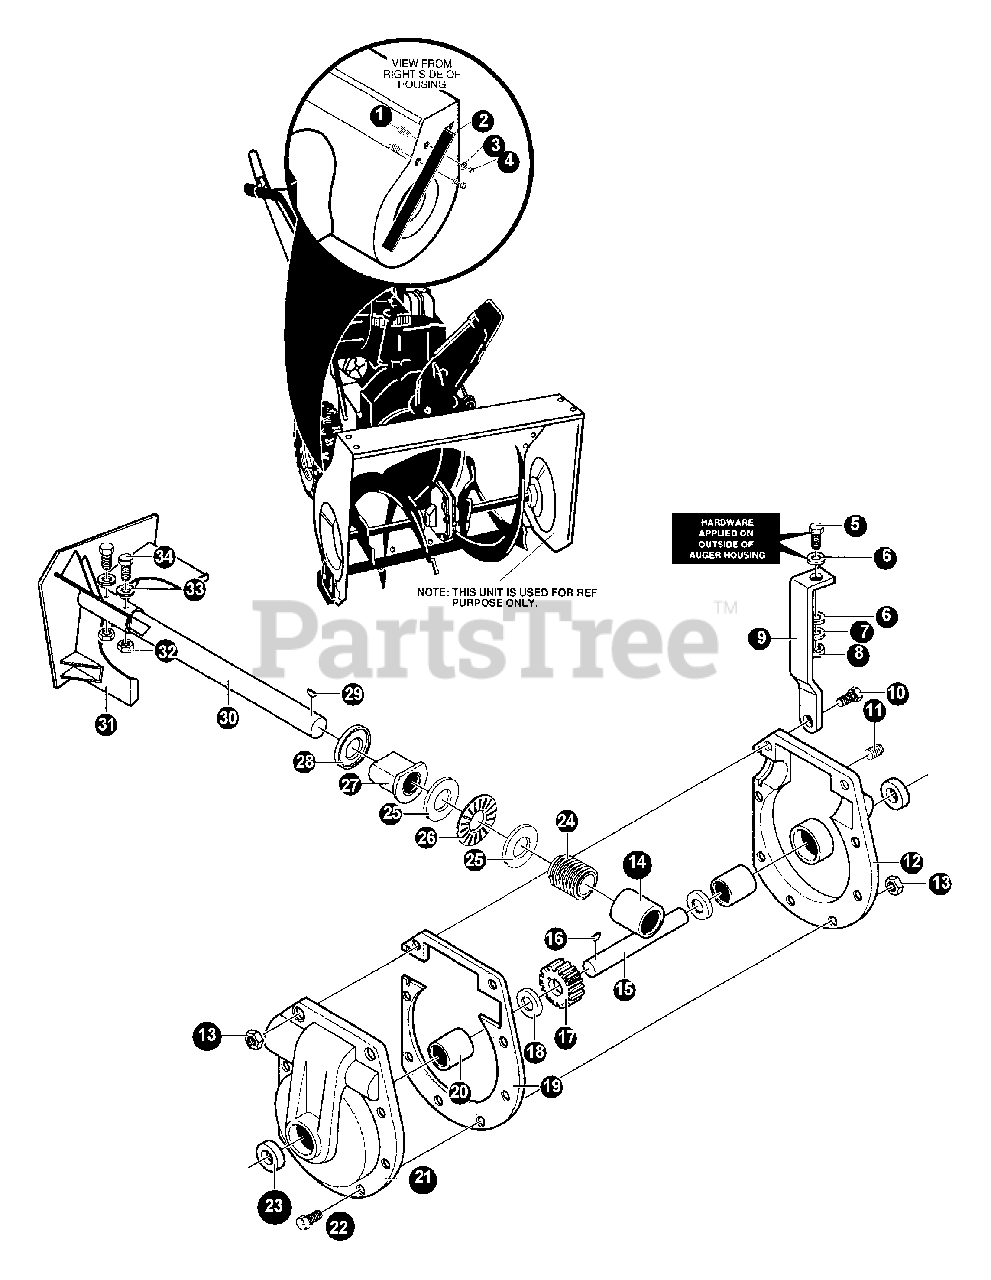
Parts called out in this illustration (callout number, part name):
1	BOLT, CARRIAGE 5/16-18×0.75
2	BAR, DRIFT CUTTER
3	WASHER
5	SCREW - 5/16-18×1.25" -- HEX HEAD CAP
6	WASHER
7	WASHER
9	BRACE, GEAR BOX
10	SCREW - 5/16-24×1.75" -- HEX HEAD CAP
11	PLUG
12	CASE, GEAR - LEFT
13	NUT, 5/16"-24
14	BEARING, SLEEVE 0.752IDX0.88ODX0.755
15	SHAFT, AUGER OUTPUT LF 32"
16	KEY, WOODRUFF
17	GEAR, WORM
18	WASHER, FLAT
19	GASKET, GEAR BOX
20	BEARING, SLEEVE
21	CASE, GEAR - RIGHT
22	SCREW 5/16"-24
23	SEAL, OIL
24	GEAR, WORM
25	WASHER, FLAT
26	BEARING, ROLL
27	BEARING, FLANGE 0.753IDX1.128OD1.03
28	RING, QUAD
29	KEY, HI-PRO 606 0.75DIAX0.187WD
30	SHAFT, WORM
31	IMPELLER ASSY
32	NUT, 1/4"-20
33	WASHER
34	SCREW 1/4"-20×2.25
